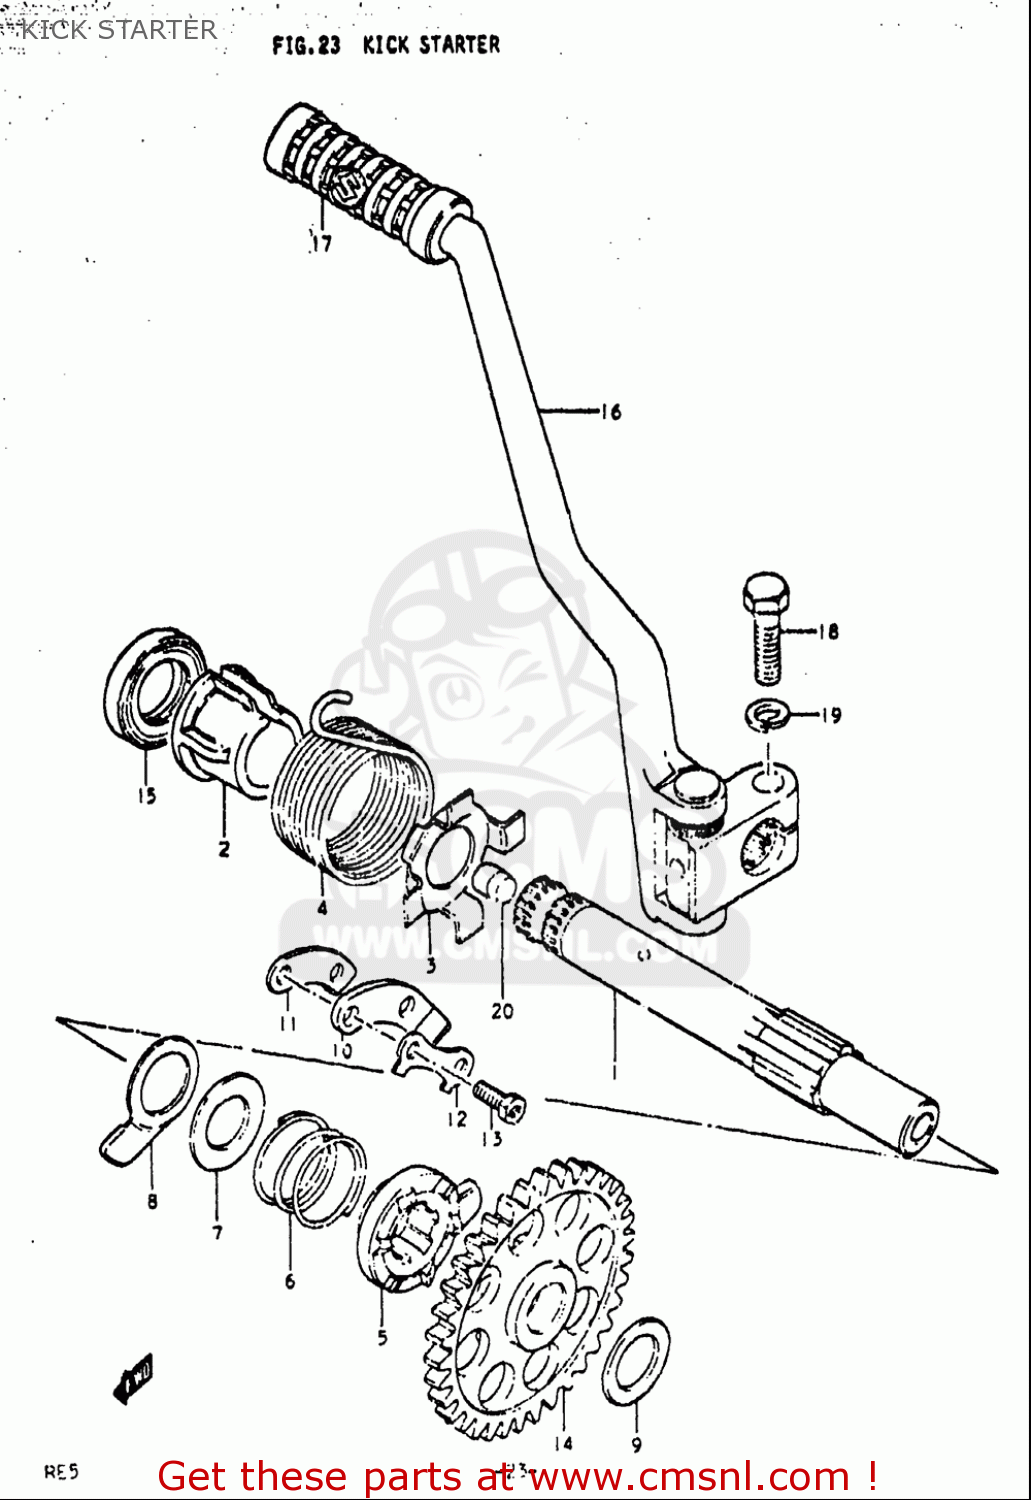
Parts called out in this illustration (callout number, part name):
3	HOLDER,KICK SHAFT SPRING
4	SPRING
5	STARTER,KICK
6	SPRING
9	WASHER
13	BOLT
15	SEAL,OIL(20X37X7)
16	LEVER ASSEMBLY,KICK STARTER
17	RUBBER,KICK STARTER PEDAL
18	BOLT
19	WASHER,LOCK
20	PLUG
